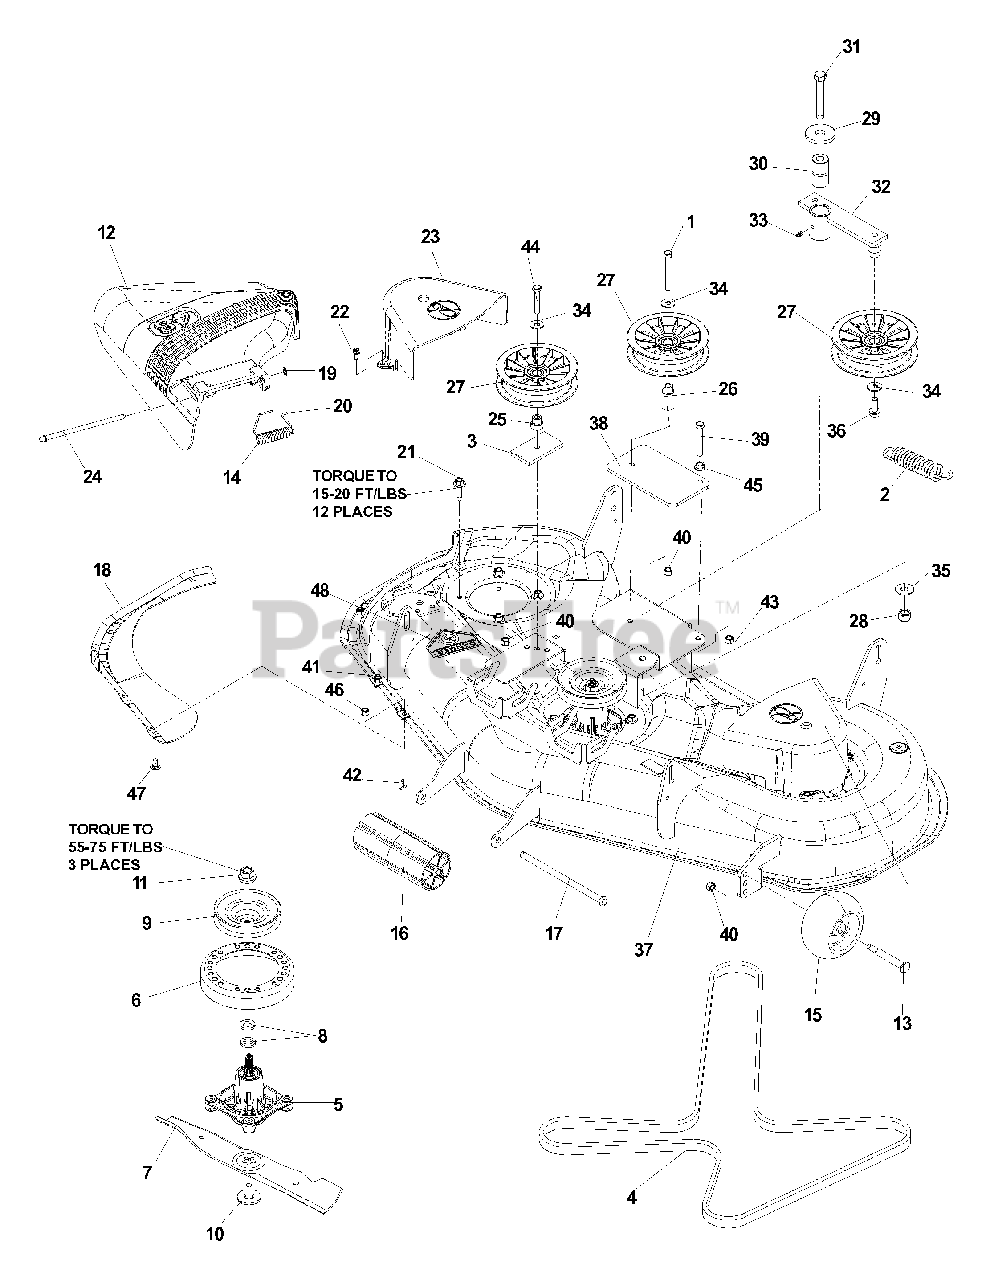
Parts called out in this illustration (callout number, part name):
1	HCS, 3/8-16, GR5
2	SPRING, EXTENSION
3	PAD
4	BELT, DECK
5	CUTTER HOUSING
6	STRIPPER, ROUND, UNIVERSAL
7	BLADE, HIGH LIFT
8	WASHER, .675 X .915 X .155, SPACER
9	PULLEY, DRIVEN
10	BOLT, 7/16, SPEC
11	NUT, 9/16, CENTERLOCK, GR5
12	DISCHARGE CHUTE
13	SB, 1/2 X 2 5/8, SPEC
14	SPRING, TORSION
15	WHEEL, GAUGE
16	ROLLER, NOSE
17	ROD, TOLLER, NOSE, NARROW
18	BAFFLE
19	NUT, 5/16, PUSH
20	CAP-SLEEVE
21	SCREW, 5/16-18 X 1 3/8, WASH HD, SPEC.
22	SCREW, 1/4-20 X 5/8, THDROLL, SPEC
23	BELTSHIELD
24	ROD HINGE
25	IDLER BUSHING
26	IDLER BUSHING
27	IDLER PULLEY, NYLON
28	NUT, 1/2-13, NYLOC
29	WASHER, .65 X 2 X .25, SUPPORT
30	BUSHING-PIVOT
31	HCS, 1/2-13 X 3 1/4, GR5
33	ZERK, STRAIGHT, 1/4-28
34	WASHER, 3/8
35	WASHER, .562 X 1.38 X 14
36	HCS, 3/8-16 X 1, GR5, WHIZLK
37	DECK W/DECALS
38	SUPPORT PLATE
39	HCS, 3/8C X 2 1/2, GR8
40	NUT, 3/8-16, NYLOC
41	HCS, 5/16-18 X 3/4, GR5
42	PIN COTTER, 1/8 X 3/4
43	NUT, 3/8-16, CENTERLOCK
44	HCS, 3/8-16 X 2, GR5
45	NUT, 3/8-16, WHIZLK
46	NUT, 5/16-18, NYLOC
47	RHSNB, 5/16-18 X 5/8, GR5
48	DECAL, WARNING
